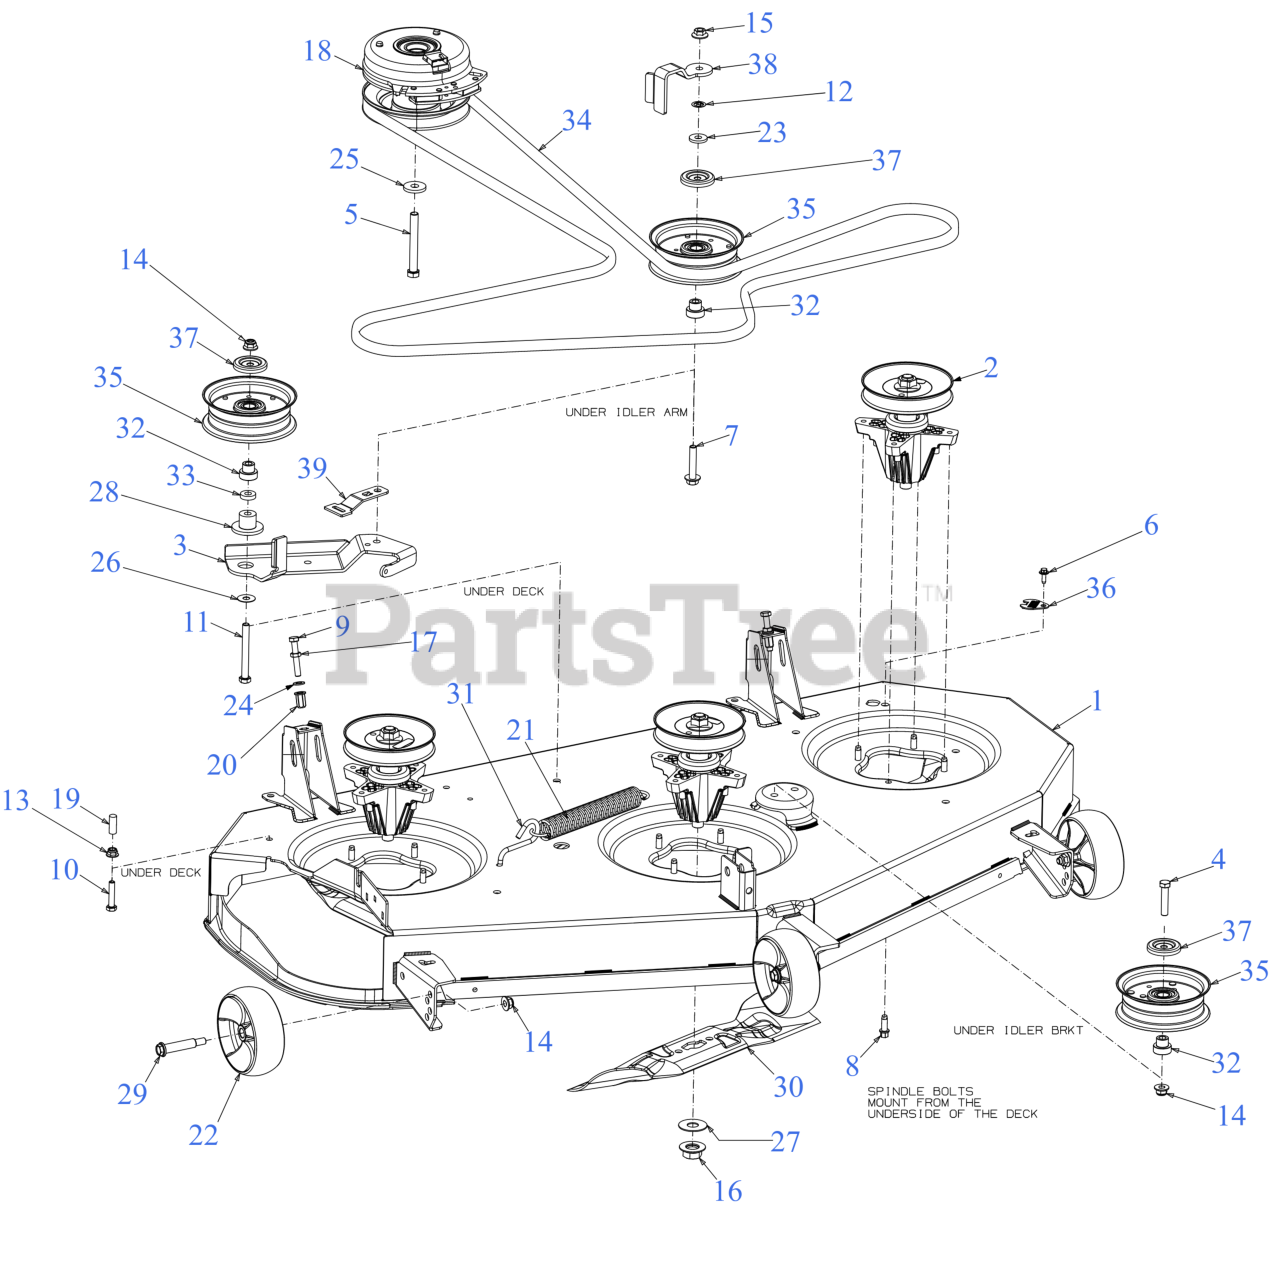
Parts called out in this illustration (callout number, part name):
1	50" FAB DECK SHELL
2	SPINDLE ASSEMBLY (5.37 DIA)
3	DECK IDLER BRACKET
4	HEX SCREW 3/8-16 x 1.75 GR5
5	SCREW 7/16-20 x 3.5 GR5
6	SCREW M6-1 x .625
7	SCREW 3/8-16 x 2.0
8	SCREW 5/16-18 x .875
9	SCREW-FULL THREAD 5/16-18 GR5
10	SCREW 5/16-18 x 1.5 LG
11	SCREW 3/8-16 x 3.25 GR8
13	FLANGE LOCK NUT 5/16-18
15	FLANGE LOCK NUT
16	HEX FLANGE NUT 5/8-18 GR5
18	ELECTRIC PTO CLUTCH
20	NUT RIVET 5/16-18
21	EXTENSION SPRING
22	DECK WHEEL (5.0 DIA x 1.875)
23	FLAT WASHER .385 x 1.00 x .135
24	FLAT WASHER
25	FLAT WASHER .445 x 1.248 x .170
26	FLAT WASHER
27	FLAT WASHER .635X1.585X.062 HDN
28	SHOULDER SPACER
29	SHOULDER BOLT (.50 X 2.0 x 3/8 -16)
30	17.271" BLADE (2IN1) (S SHAPE CENTER HOLE)
30	Cub Cadet 50" HI LIFT BLADE SET (S SHAPE CENTER HOLE)
30	Troy-Bilt 50" HI LIFT BLADE SET (S SHAPE CENTER HOLE)
30	17.271" XTREME BLADE (2IN1) (S SHAPE CENTER HOLE)
30	Cub Cadet 50" XTREME BLADE SET (S SHAPE CENTER HOLE)
30	Troy-Bilt 50" XTREME BLADE SET (S SHAPE CENTER HOLE)
30	17.271" LOW LIFT (S SHAPE CENTER HOLE)
31	DECK SPRING HOOK
32	SHOULDER SPACER
34	V-BELT B SEC x 143.5 LG
34	Cub Cadet 50" DECK DRIVE BELT
34	Genuine Factory Parts 50" DECK BELT
34	Troy-Bilt 50" DECK DRIVE BELT
35	IDLER PULLEY 4.50" DIA
36	DECK WASH PLUG
37	IDLER PULLEY CAP
38	BELT KEEPER
